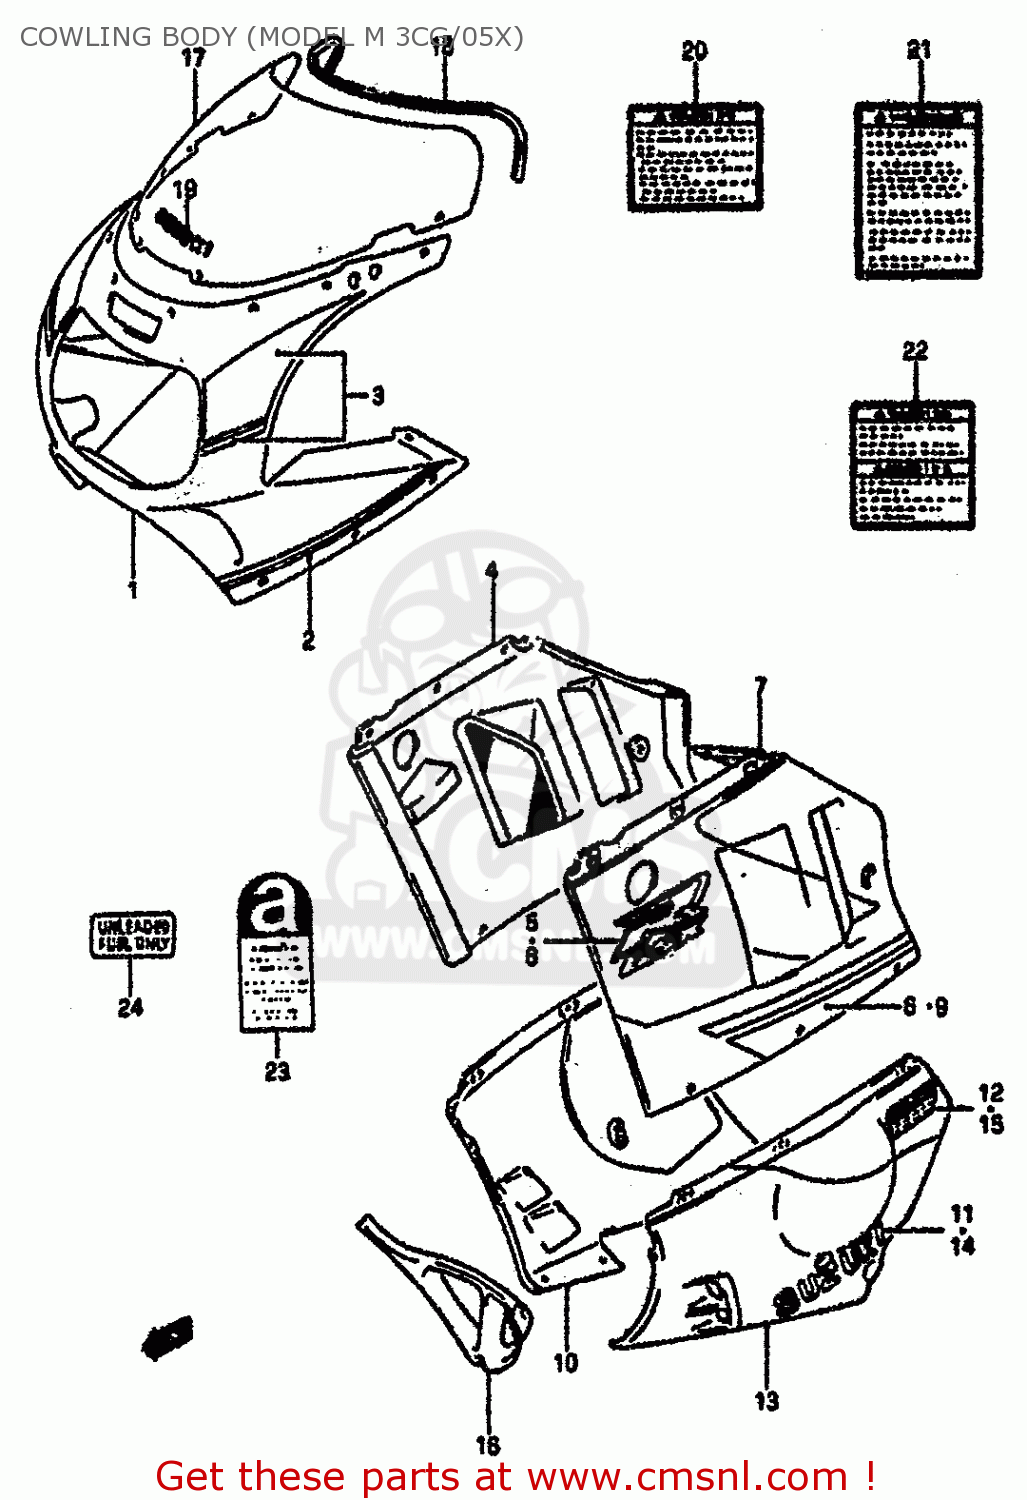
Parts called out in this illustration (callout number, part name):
1	BODY ASSY,COWLING
2	TAPE SET, SIDE
3	TAPE SET, FRONT
4	COVER,COWLING SIDE,R
5	EMBLEM,COWLING SIDE
6	TAPE, SIDE RH
7	COVER,COWLING SIDE,L
8	EMBLEM,COWLING SIDE
9	TAPE, SIDE LH
10	COWLING,UNDER,R
11	EMBLEM,SUZUKI
12	EMBLEM,SACS
13	COWLING,UNDER,L
14	EMBLEM
15	EMBLEM,SACS
16	COWLING,UNDER,CENTER (B
17	SCREEN SET,WIND
18	MOLDING
19	EMBLEM,SUZUKI(WHITE)
20	LABEL, WARNING SAFETY
21	LABEL (WARNING SCREEN)
22	LABEL (WARNING)
23	LABEL,ASBESTOS WARNING
24	LABEL,FUEL CAUTION
